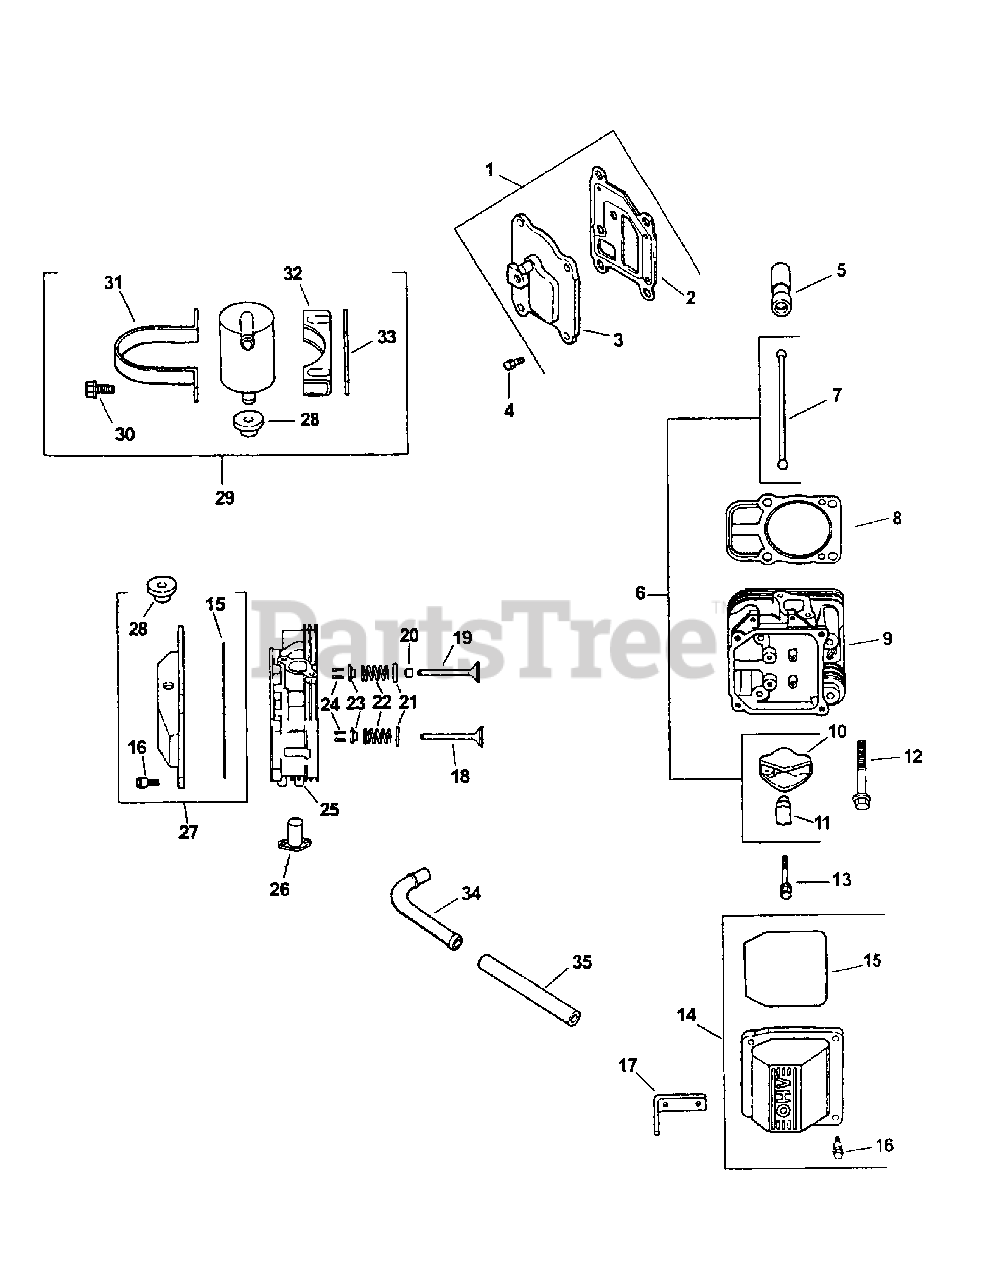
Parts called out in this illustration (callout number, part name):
1	Kit, Breather Cover w/Gaskets
2	Gasket, Breather
3	Cover, Breather
4	Screw, Hex Flange
5	Lifter, Valve
6	Kit, Valve Train
7	Rod, Push
8	Gasket, Cylinder Head
9	Head Assembly, #2 Cylinder
10	Arm, Rocker
11	Pivot, Rocker Arm
12	Screw, Hex Flange
13	Screw, Hex Flange
14	Kit, Valve Cover - Plain
16	Screw, Shoulder
17	Strap, Lifting
18	Valve, Exhaust (Std.)
18	Valve, Exhaust (.25)
19	Valve, Intake (Std.)
19	Valve, Intake (.25)
20	Seal, Valve Stem
21	Retainer, Spring
22	Spring, Valve
23	Cap, Valve Spring
24	Kit, Retainer
25	Head Assembly, #1 Cylinder
26	Liner, Exhaust Port
27	Kit, Valve Cover - Breather
28	Grommet, Rubber
29	Kit, Breather Separator
30	Screw, Hex Flange
31	Strap, Breather
32	Bracket, Breather Separator
35	Hose, Flexible
